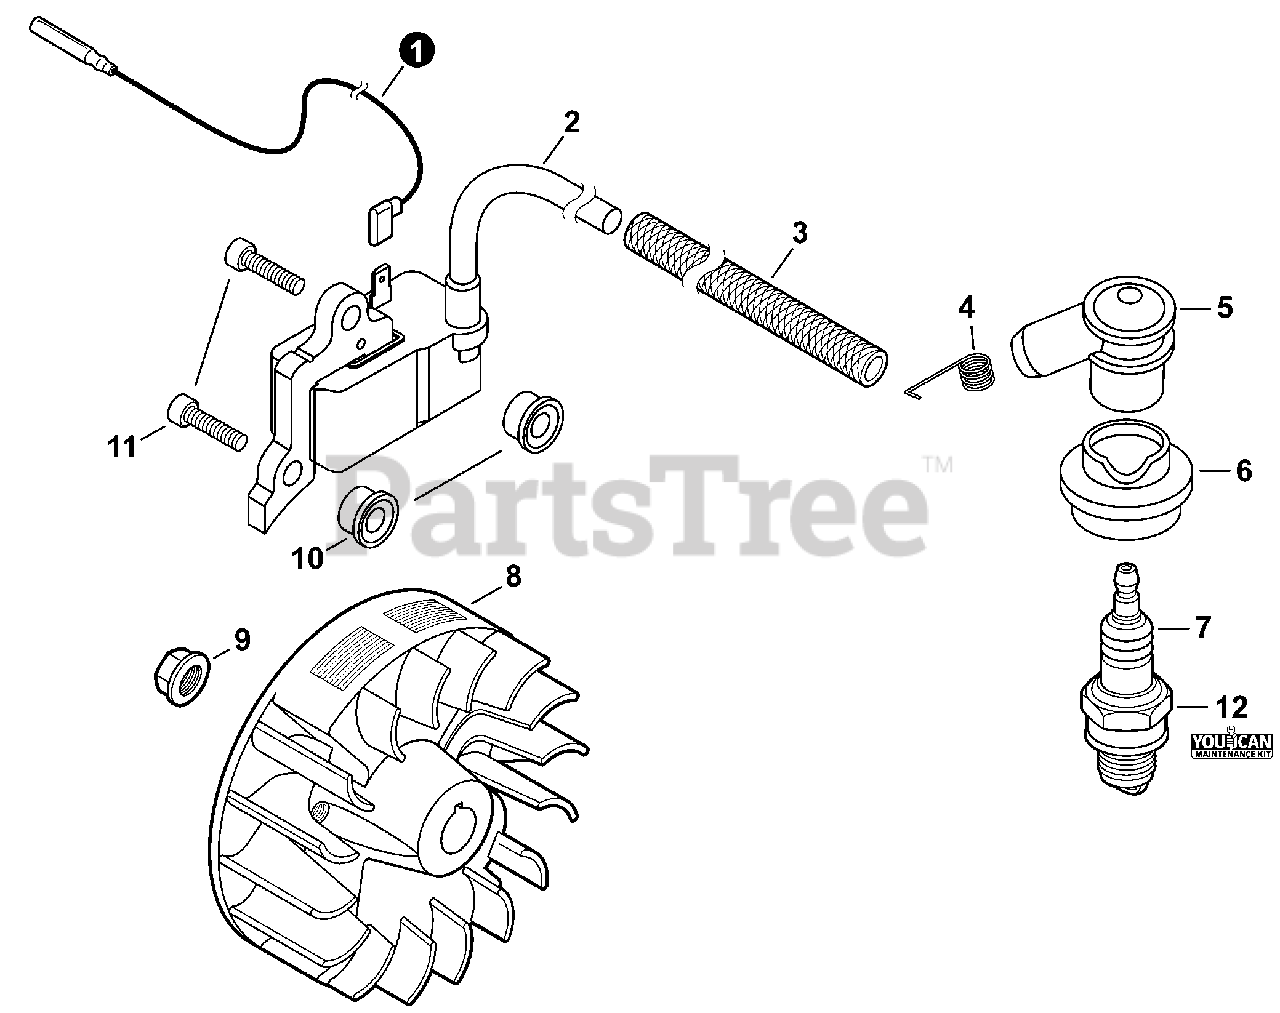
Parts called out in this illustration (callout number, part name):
2	COIL, IGNITION
3	TUBE, INSULATOR
4	TERMINAL, SPARK PLUG
5	CAP, SPARK PLUG
6	SEAL, SPARK PLUG
7	SPARK PLUG - CMR7H
8	FLYWHEEL
9	NUT, FLANGE M8
10	WASHER 5
11	BOLT 5×20
12	TUNE-UP KIT - YOUCANT
